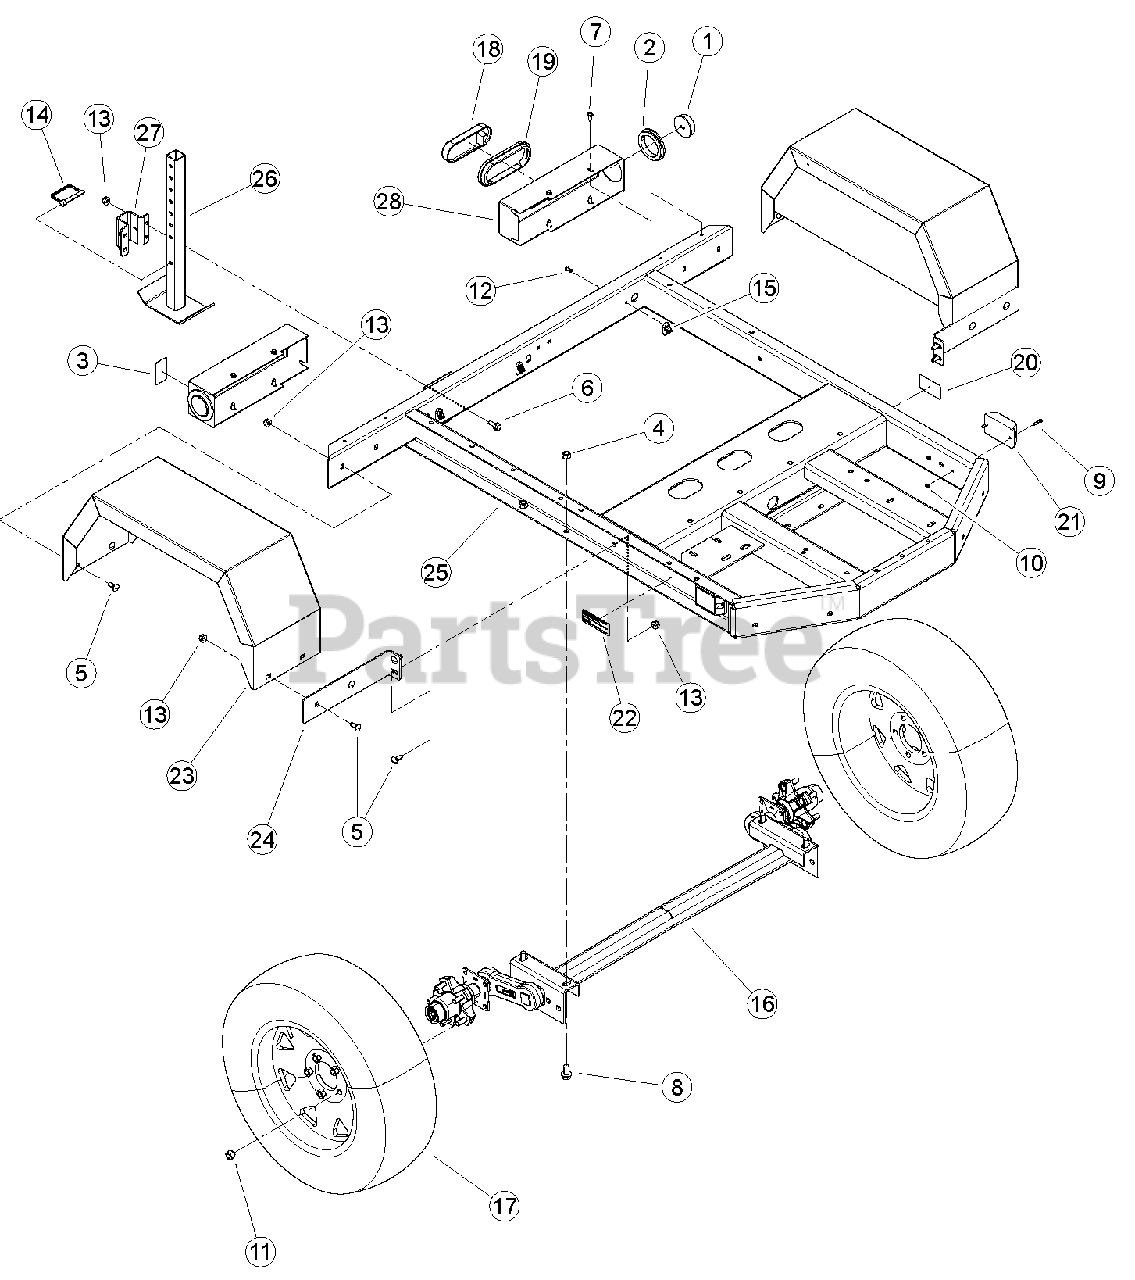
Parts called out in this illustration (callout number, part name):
1	LIGHT, RED CLEARANCE
2	GROMMET, CLEARANCE LIGHT
3	REFLECTOR, WIDE ANGLE RED
4	NUT, 1/2" CENTERLOCK GRB ZP
5	BOLT, 3/8 X 1" GR5 CRG NC ZP
6	BOLT, 3/8 X 1 FLANGE NC
7	SCREW, 11/32 X 7/8 HWH AB THREAD ZP
8	BOLT, 1/2-13 1.00 GR5 FLANGE NC
9	SCREW, MCH 10-24 X 1" RND HD PHL ZP
10	NUT, 10/24 NYLOCK TYPE NM ZP
11	NUT, 1/2-20 WHEEL
12	RIVET, AL BLIND 1/4 X 3/4 DOME HEAD
13	NUT, 3/8-16 NYLOCK FLANGE
14	PIN, 3/8 X 2-3/4" SNAP
15	CLAMP, CABLE MOUNT
16	AXLE, TORSION 1800
17	ASSEMBLY, TIRE AND WHEEL 14 IN
18	TAIL LIGHT, OVAL LED
19	GROMMET, OVAL TAIL LIGHT
20	DECAL, P205/75R14 LOAD RATING
21	LIGHT, AMBER MARKER
22	DECAL, EPA EVAP
23	WELDMENT, 6" CHIPPER FENDER
24	BRACKET, 6" FENDER
25	WELDMENT, 6" CHIPPER TRAILER
26	WELDMENT, REAR STABILIZER
27	GUIDE, TRAILER SUPPORT
28	BRACKET, TAILLIGHT
